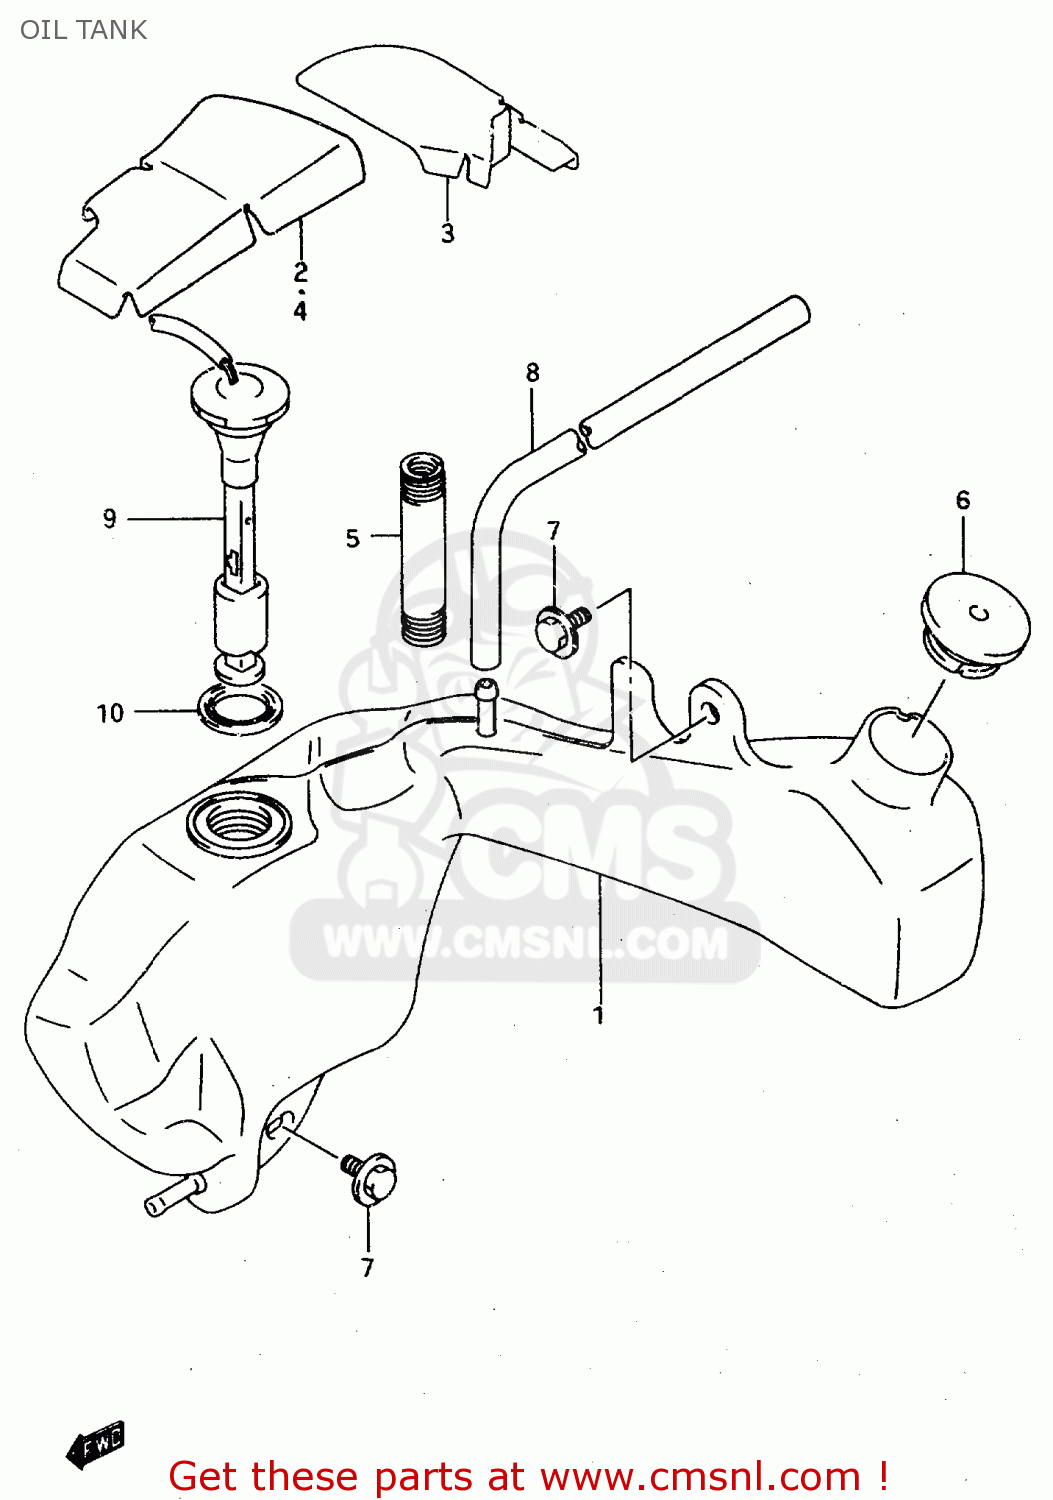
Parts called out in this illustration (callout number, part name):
1	TANK,OIL
2	SHIELD, OIL TANK
5	SHIELD,FUEL HOSE HEATER
6	CAP,OIL TANK
7	BOLT M6X16
8	HOSE(7X11X600)
9	SWITCH ASSY,OIL LEVEL
10	GASKET (NAS)
